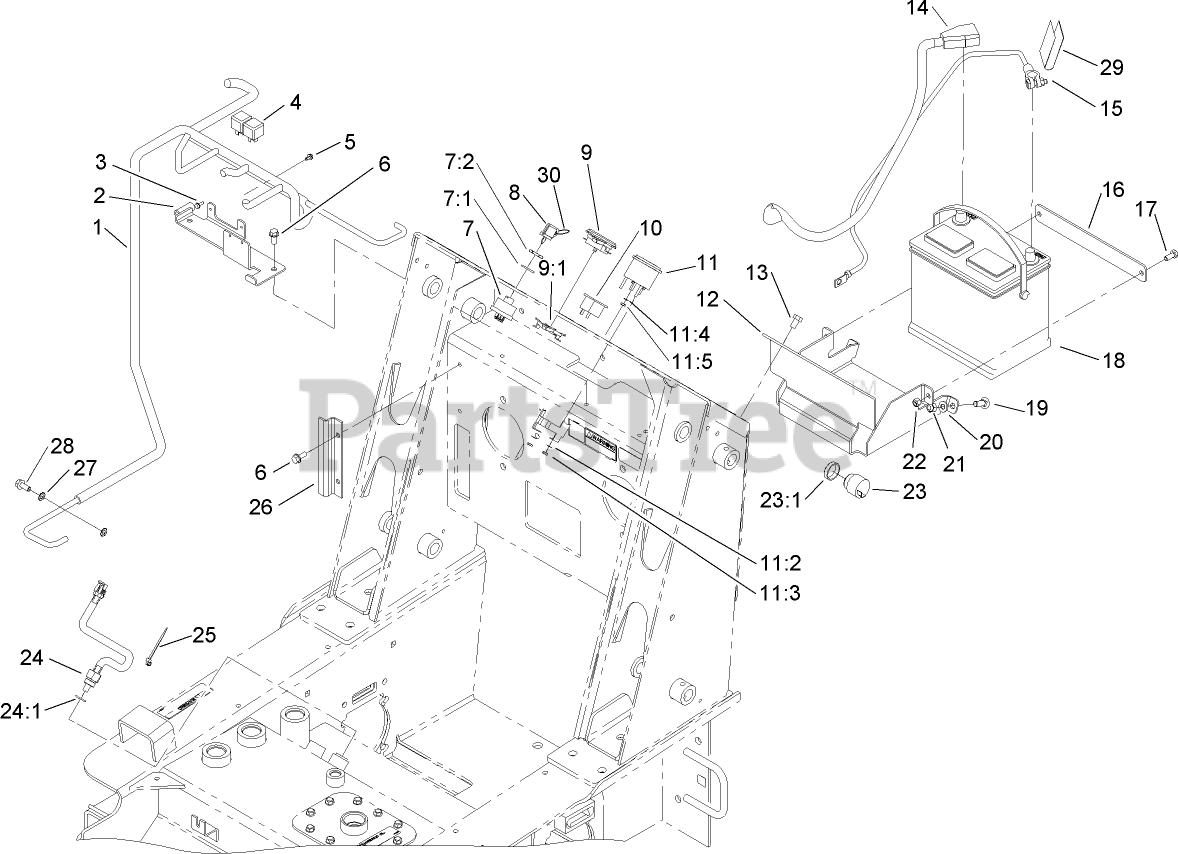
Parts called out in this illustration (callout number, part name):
1	HARNESS-WIRE
2	Fuse/Relay Bracket ASM
3	SCREW-HWH
4	RELAY
5	SCREW-HWH
6	SCREW-HWHTF
7	Key Switch ASM
7:1	WASHER-TOOTH, INTERNAL
7:2	NUT-HH
8	KEY-IGNITION
9	INDUCTIVE HOURMETER ASM
9:1	CLIP-MOUNTING
10	LIGHT-TEMP, OIL
11	GAUGE-FUEL
11:2	WASHER-LOCK, INT
11:3	NUT-HEX
11:4	WASHER-LOCK / EXT
11:5	NUT-HEX
12	TRAY-MOUNTING, BATTERY
13	SCREW-HWHTF
14	CABLE-BATTERY, POSITIVE
15	CABLE-BATTERY, NEGATIVE
16	CLAMP-BATTERY
17	SCREW-HH
18	BATTERY
19	SCREW-CARR
20	WASHER-FLAT
21	NUT-LOCK, NI
22	NUT-LOCK, NI
23	AUDIO ALARM ASM
23:1	NUT-PLASTIC, KNURLED
24	SENSOR-TEMPERATURE
24:1	O-RING
25	TIE-CABLE
26	SHIELD-WIRING
27	WASHER-LOCK
28	SCREW-HHF
29	DECAL-INSTRUCTIONS, CHARGING
30	RING-KEY
